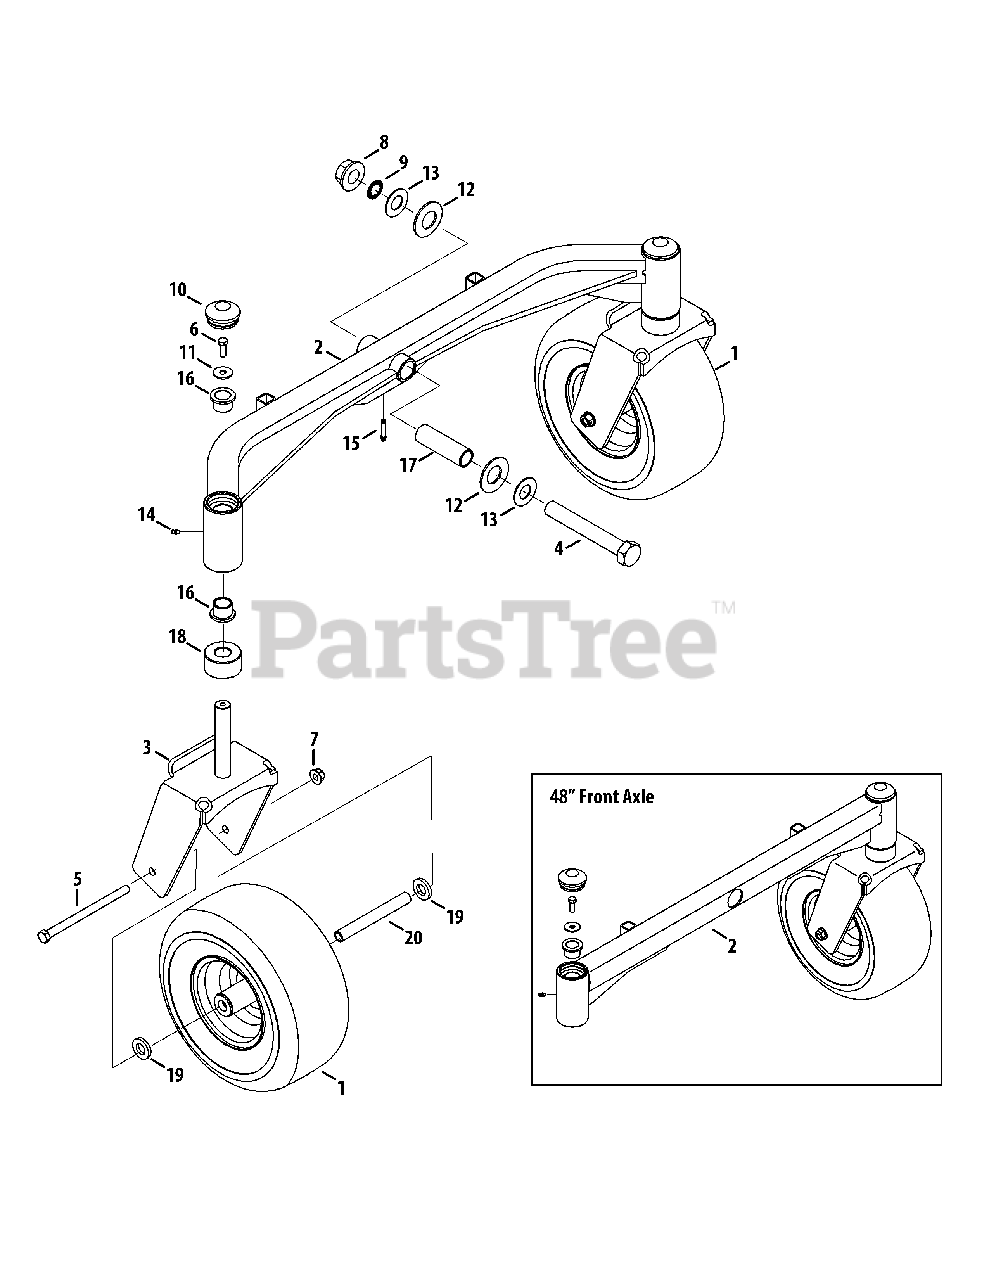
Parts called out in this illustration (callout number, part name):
1	Wheel Assembly, 13 x 6.50-6
2	Front Axle (54" & 60" deck)
2	Front Axle (48" deck)
3	Yoke, Caster Wheel
4	Hex Cap Screw, 1-14 x 7.0
5	Hex Cap Screw, 1/2-13 x 7.75
6	Hex Cap Screw, 3/8-16 x 1.00
7	Nut, 1/2-13, Flangelock
8	Nut, 1.0-14, Flangelock
9	Retainer Ring
10	Axle Grease Cap
11	Washer, .411 x 1.25 x .100
12	Bell Washer, 1.25 x 2.50 x .180
13	Washer, 1.00 x 2.00 x .075
14	Grease Fitting, 1/4-28
15	Grease Fitting, 1 39/64
16	Bearing, 1.001 x 1.25
17	Spacer, 1.005 x 1.247 x 4.1
18	Spacer, Spacer, 1.010 x 2.45 x 1.298
19	Spacer, .812 ID x .218 LG
20	Spacer, .515 x .749 x 6.313
